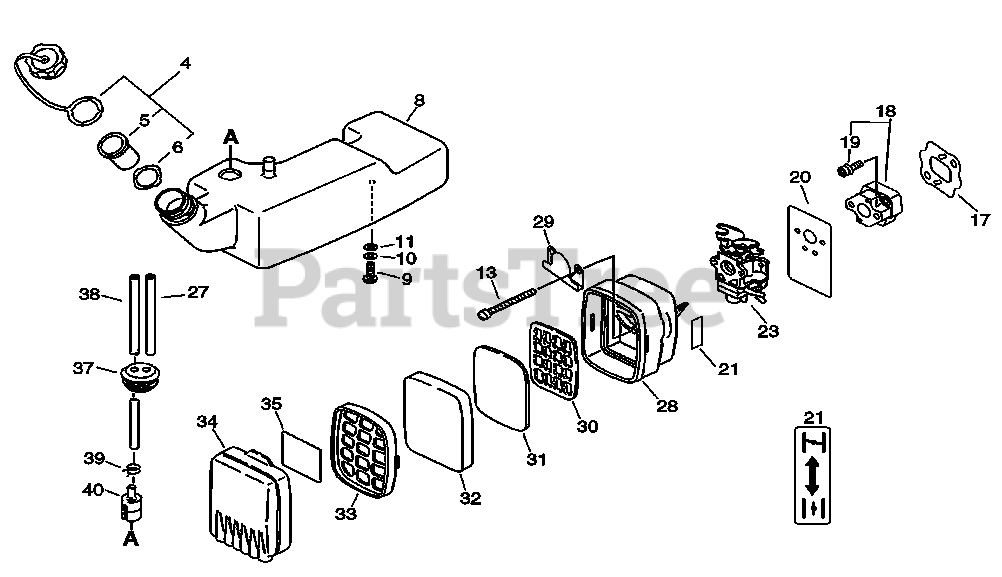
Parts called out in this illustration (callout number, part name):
4	CAP ASSY
5	VENT, CAP
6	GASKET, CAP
8	TANK, FUEL
9	SCREW - 6X14
10	LOCKWASHER - 6
11	WASHER - 6.5
13	SCREW - 5X60
17	GASKET, INTAKE
18	INSULATOR KIT
19	SCREW - 5X30
20	GASKET, INTAKE
21	LABEL - CHOKE
23	CARBURETOR WYK-200
27	PIPE - 3X6X145 -- CLEAR
28	CASE, AIR FILTER
29	PLATE, PREVENT
30	RETAINER, AIR FILTER
31	FILTER, AIR
32	PRE-FILTER -- FOAM
33	RETAINER, AIR FILTER
34	COVER, AIR FILTER
35	LABEL - AIR FILTER
38	PIPE - 3X6X280 -- BLACK
39	CLIP - 6.5
40	FILTER, FUEL
